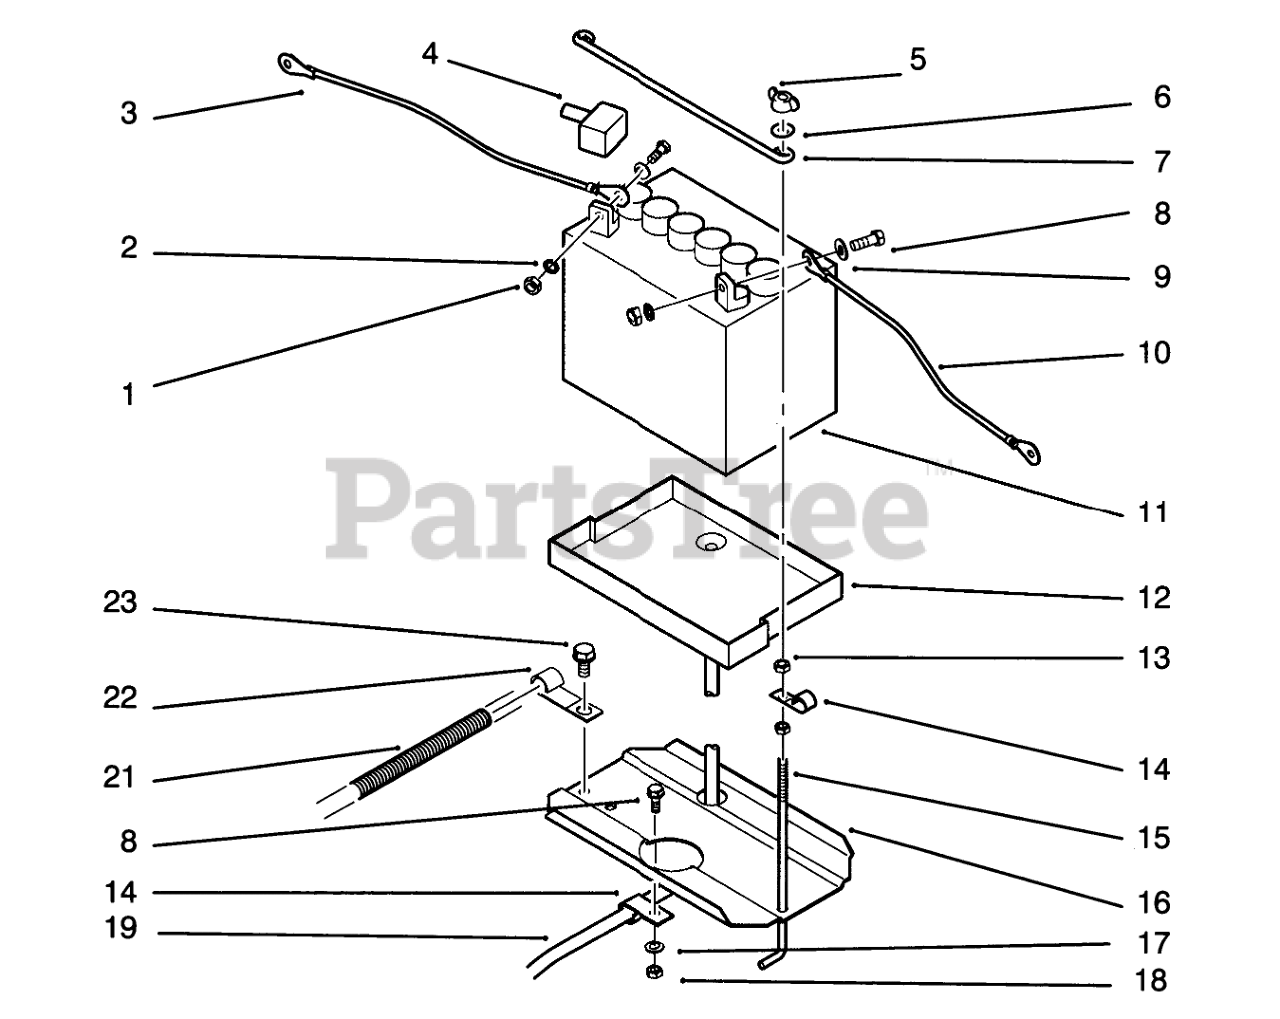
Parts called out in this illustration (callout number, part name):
1	NUT-HEX
2	Washer
3	ASS'Y-WIRE
4	Boot
5	NUT-WING
6	WASHER-FLAT
7	ROD-BATTERY HOLD DWN
8	SCREW-HH
9	WASHER-FLAT
10	WIRE -BLACK
11	Battery
12	TRAY-BATTERY
13	Nut
14	CLAMP
16	Tray
17	WASHER-FLAT
18	NUT-LOCK, NI
19	TUBE-21" BATTERY DRAIN
21	WIRING-HARNESS
22	CLIP
23	Screw
